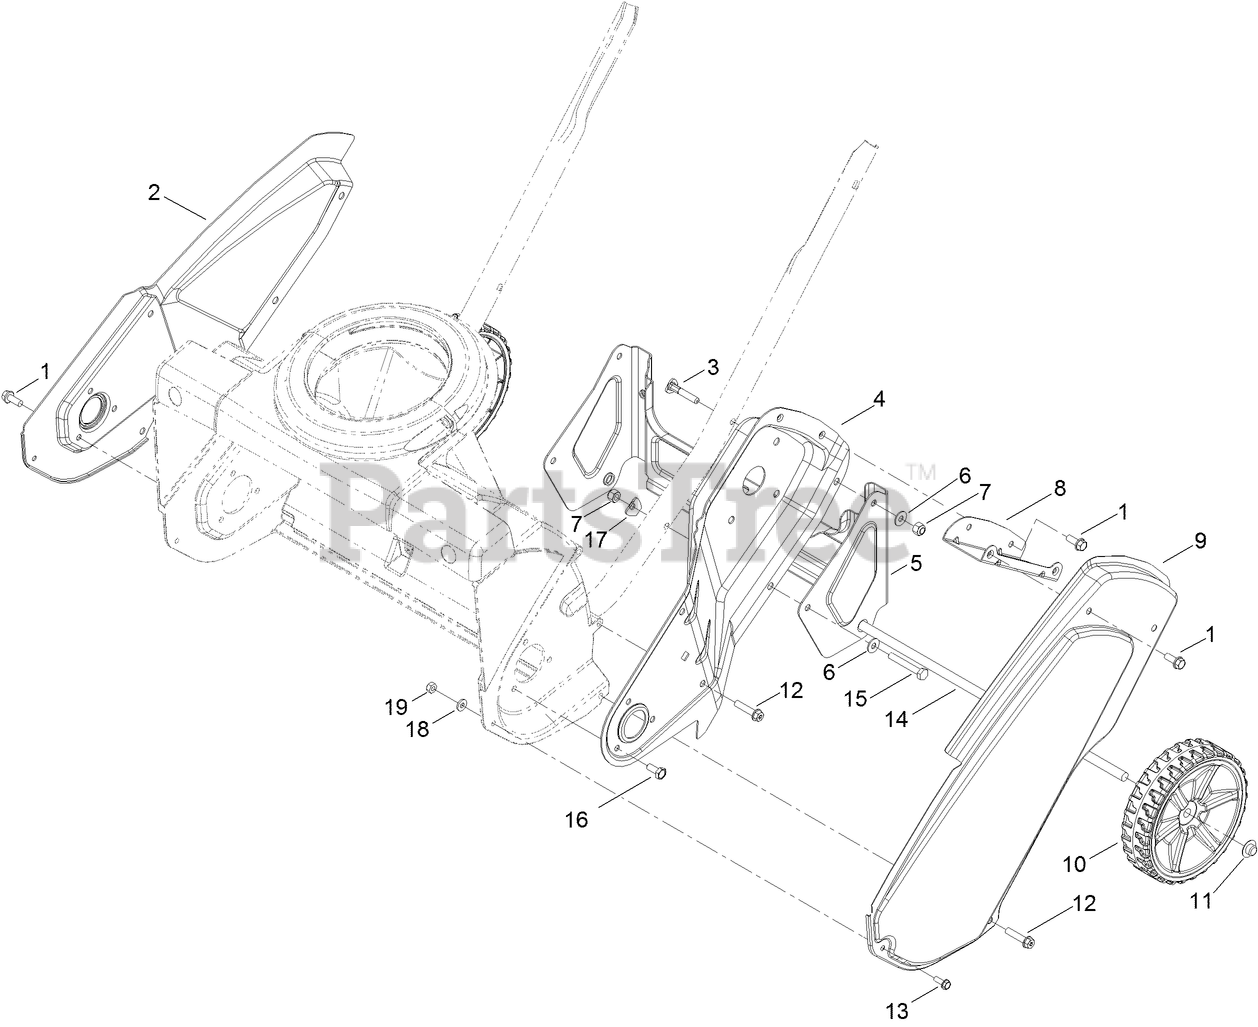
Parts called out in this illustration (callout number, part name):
1	SCREW-HWH
2	SIDEPLATE-RH
3	SCREW-HANDLE
4	SIDEPLATE-LH
5	BRACKET-WHEEL
6	WASHER-FLAT
7	NUT-LOCK, NI
8	BRACKET-COVER, BELT
9	COVER-BELT
10	WHEEL ASM
11	NUT-PUSH
12	SCREW-PLASTIC
14	AXLE
15	SCREW-HH
16	SCREW-HH, TAPTITE
17	WASHER
18	WASHER-FLAT
19	NUT-LOCK, NI
